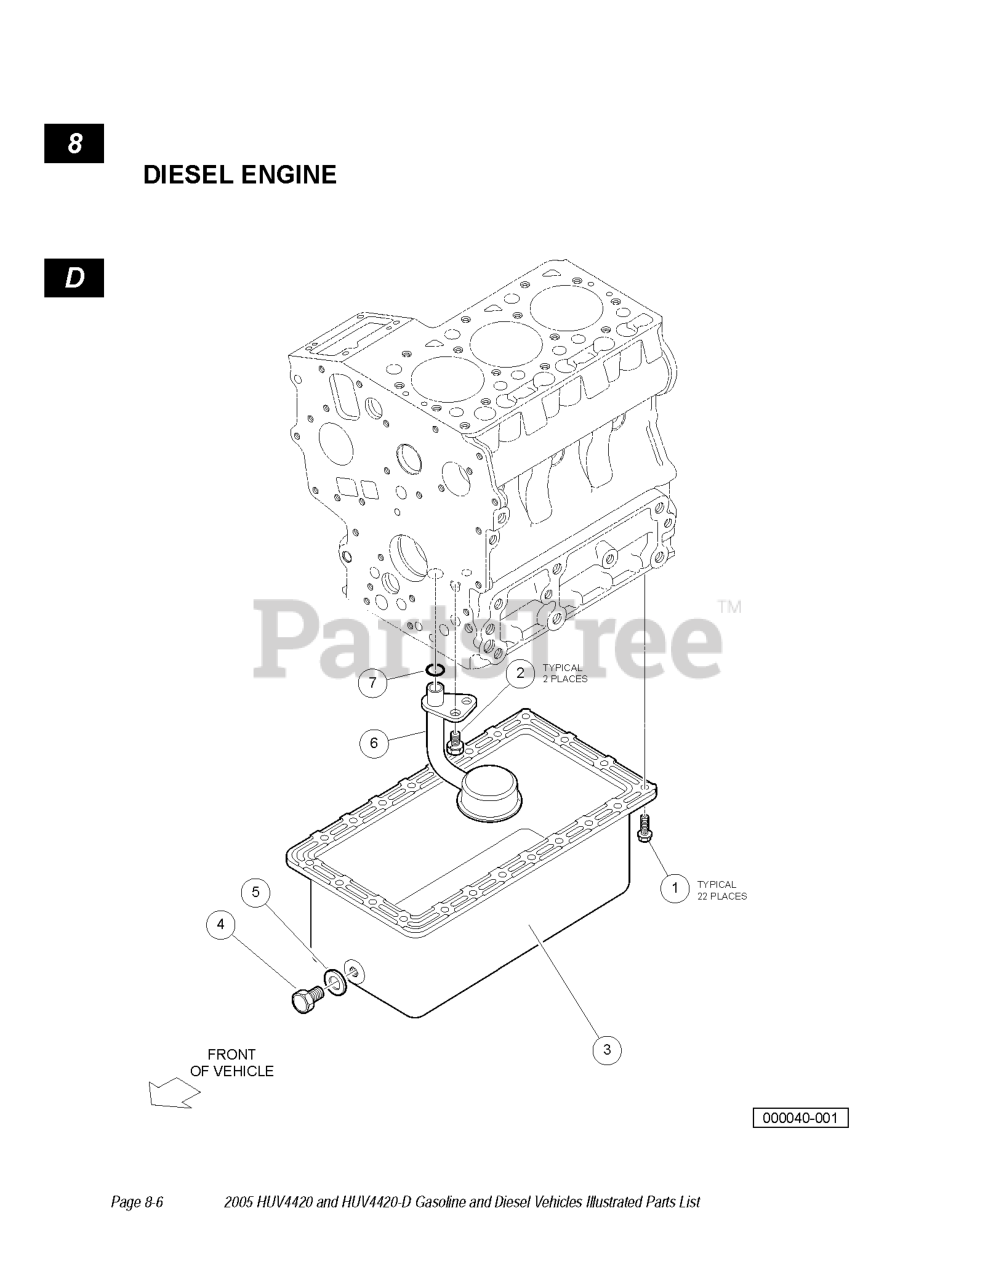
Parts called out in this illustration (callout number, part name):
1	BOLT, M6 X 1 X 14
2	BOLT, M8 X 1.25 X 15
3	COMP, OIL PAN
4	PLUG, DRAIN, M12 X 14
5	GASKET, 20 X 13
6	FILTER, OIL, PICK UP
7	O RING, 20 X 17
